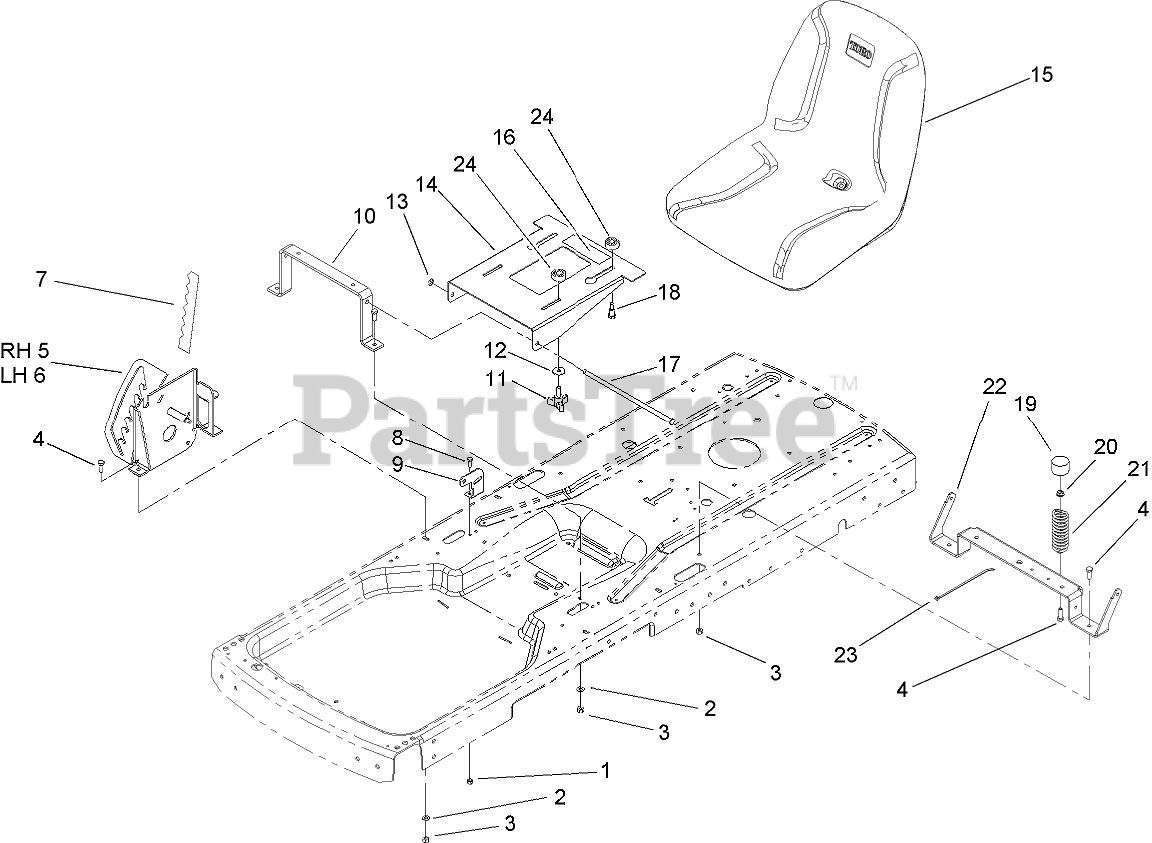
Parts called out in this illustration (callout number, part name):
1	NUT-LOCK, NI
2	WASHER-PLAIN
3	NUT-LOCK, NI
4	SCREW-HH
5	RH PLATE ASM
6	LH PLATE ASM
7	DECAL-HOC
8	SCREW-HH
9	BRACKET-BELLCRANK
10	BRACE-SEAT, FRONT
12	WASHER-PIVOT
13	E-RING
14	BRACKET-SEAT
15	SEAT
16	DECAL-SERVICE, CE
17	PIN-PIVOT
18	SCREW-SHOULDER
19	CAP-PROTECTOR
20	NUT-HF
21	SPRING-COMPRESSION
22	BRACE-SEAT, REAR
23	TIE-CABLE
24	SPACER-NYLON
